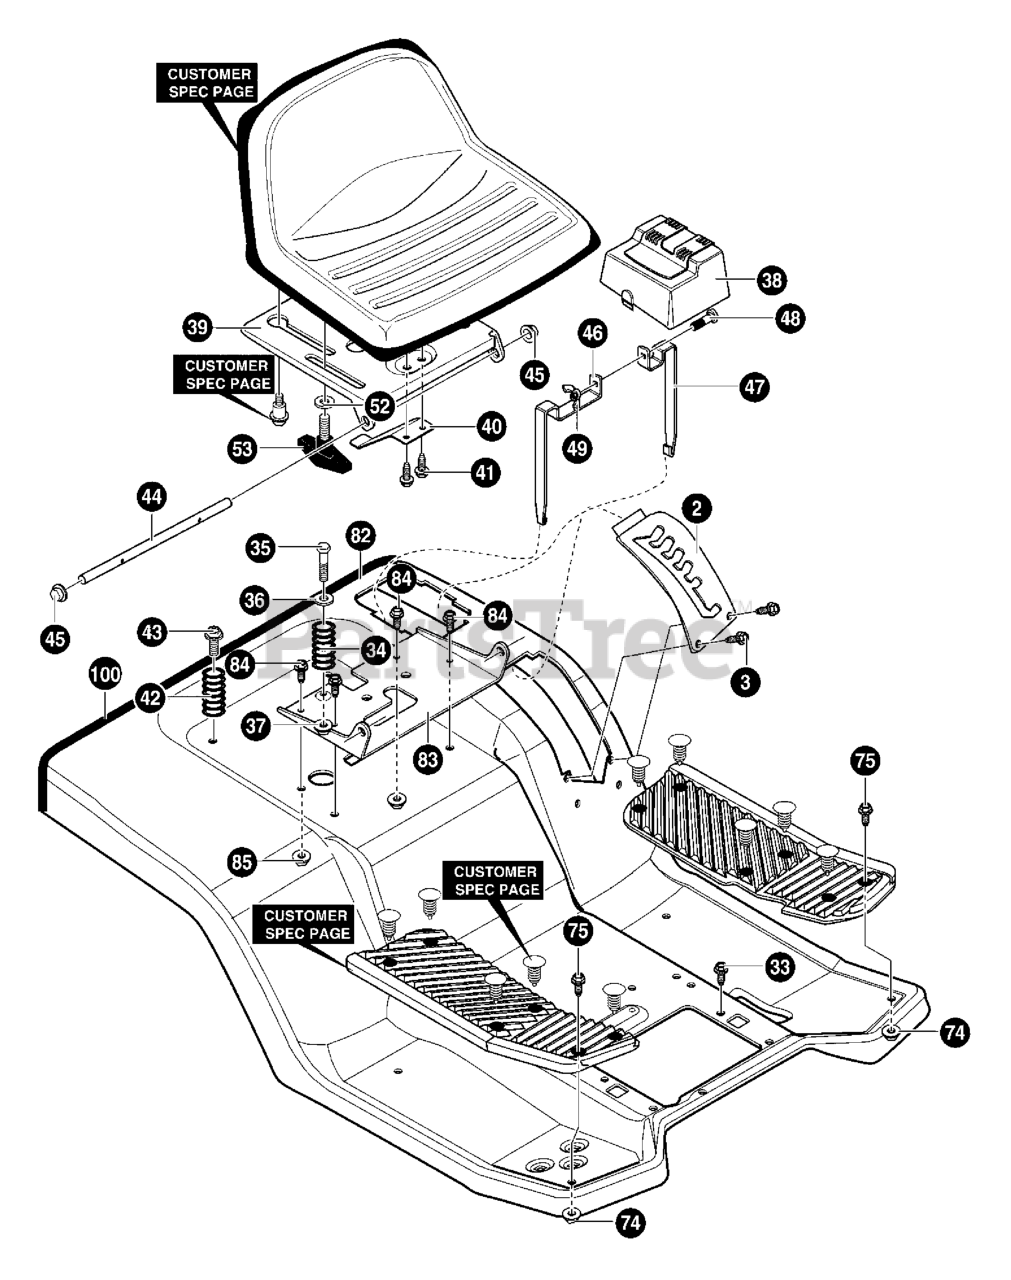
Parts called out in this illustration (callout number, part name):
2	PLATE-LIFT DETENT 5 POS, REBA
3	SCREW, #12X.50 PHPNHTAP
34	SPRING, COMP. 4.57LGX1.17
35	BOLT, SHOULD 1/4-20
36	ZINC WASHER CUP
37	NUT, CTRLK 1/4-20
38	COVER, BATTERY
39	SUPPORT, SEAT
40	SPRING - LEAF
41	SCREW, 1/4-20X.50 HWDFLLK MACK
42	SPRING, COMP 2.43LG
43	SCREW, 5/16-18 x 0.75 HHWATAP
44	ZINC HINGE SEAT PIVOT
45	NUT, PUSH CAP .375
46	BATTERY BRACKET L.H.
47	BATTERY BRACKET R.H.
48	BOLT, 1/4-20X.63 CARR.
49	NUT, WING 1/4-20
52	WASHER, FLAT .344X.62X.06
53	BOLT, WING 5/160-18X.50
74	NUT, 5/16-18 HEXWDFLLK WHIZ
75	BOLT, 5/16-18X.75 CARR.
82	SEAT DECK PEDAL HYDRO
83	BRACKET, SEAT PIVOT
84	SCREW, 5/16-18 x 0.75 HHWATAPSGIBP
85	NUT, 5/16-18 HWDFLLK
100	TRIM, STRIP
